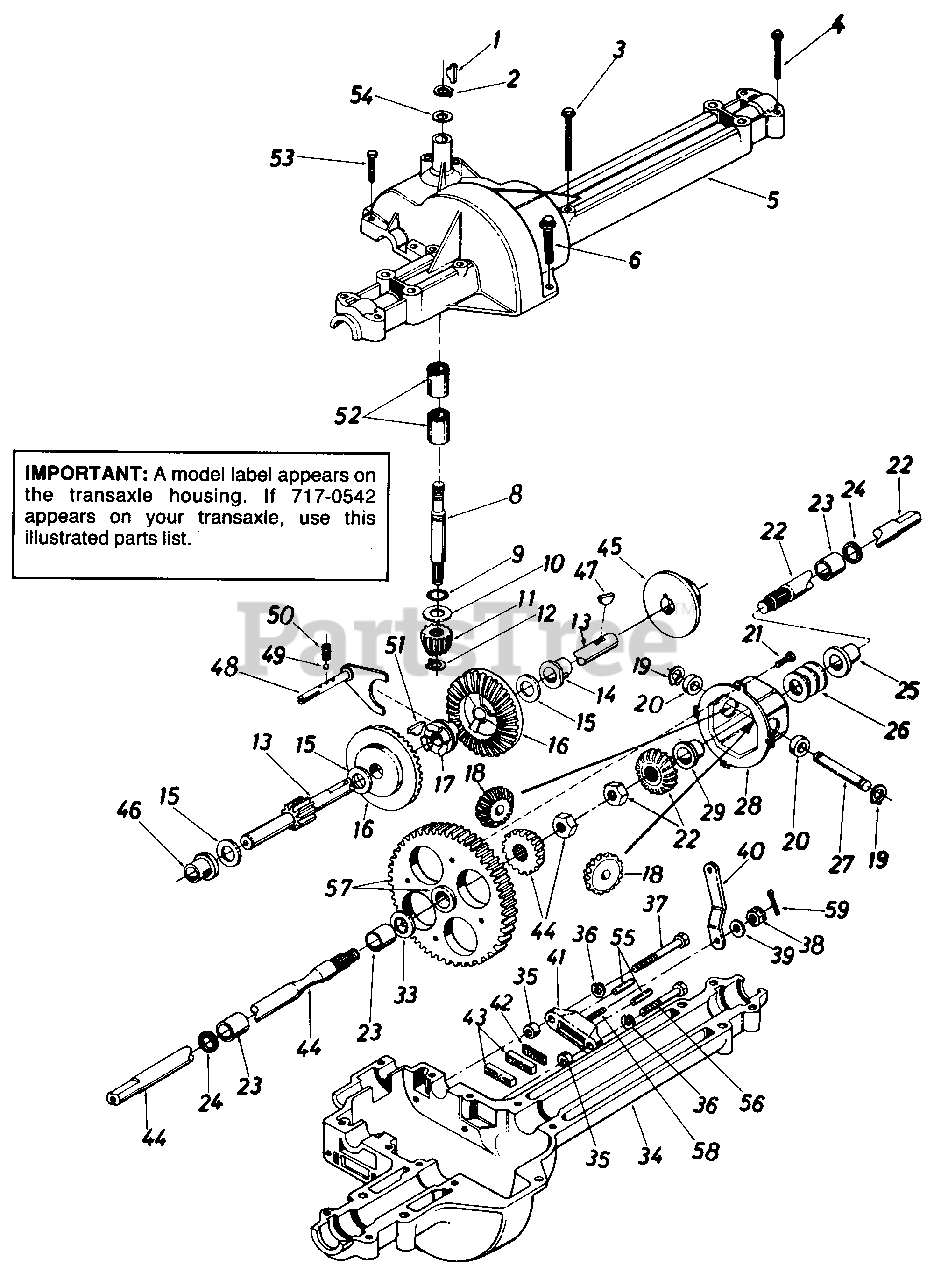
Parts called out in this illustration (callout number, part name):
1	#4 Hi-Pro Key 3/32 x 5/8" Dia.
2	Snap Ring .625" Shaft
3	Hex Bolt 1/4-20 x 1.75" Lg.
4	Hex Bolt 1/4-20 x 1.25" Lg.
5	Upper Housing
6	Hex Fl-Bolt 1/4-20 x .75" Lg.
9	Square Seal 5/8" I.D.
10	Thrust Washer 5/8" I.D. x 1.25" O.D.
11	Pinion Input 14T
12	Retaining Ring 7/16" Ext.
13	Drive Shaft-R.H.
14	Flange Brg. 518" I.D. x 3/4" Lg.*
15	Fl-Wash.
16	Bevel Gear 42T
17	Clutch Collar
18	Miter Gear 15T
19	Retainer Ring
20	Thrust Bearing 1/2" I.D. x 1.0" O.D.
21	Pan Head Scr. 1/4-20 x .50" Lg. w/Patch
22	Axle R.H. Ass'y.
23	Sleeve Bearing 3/4" I.D. x 1.0" Lg.
24	Oil Seal 3/4" I.D.
25	Flange Bearing 3/4" I.D. x 15/16" Lg.
26	Fl-Wash. .760" I.D. x 1.49" O.D.
28	Differential Housing Ass'y.
33	Fl-Wash. .75" I.D. x 1.5" O.D.
34	Lower Housing
35	Spacer .53" O.D. x 3/8" Lg.
36	L-Wash. 1/4" I.D.
37	Hex Bolt 1/4-20 x 1.50" Lg. (Grade 5)
38	Castle Nut 5/16-24 Thd.
39	Fl-Wash. .34" I.D. x .875" O.D.
40	Actuating Arm-R.H.
42	Puck Plate
43	Brake Puck
44	Axle L.H. Ass'y.
46	Flange Bearing 5/8" I.D. x 15/16" Lg.
47	Woodruff Key 3/16 x 5/8 HT
48	Shift Fork Ass'y.
49	Ball Detent .250" Dia.
50	Spring Detent
51	#9 Hi-Pro Key 3/16" x 3/4" Dia. HT
52	Needle Brg. 5/8" I.D. x 1/2"
53	Hex Bolt 1/4-20 x 1.00" Lg.
54	Fl-Wash. 5/8" l.D. x .030
55	Actuating Pin 5/16" Dia.
56	Hex Bolt 1/4-20 x 1.50" Lg. (Grade 5)
57	Differential Gear 72T Ass'y. w/Bearing
58	Sq. Hd. Bolt 5/16-24 Thd.
59	Cotter Pin 3/32" Dia. x l.0" Lg.
